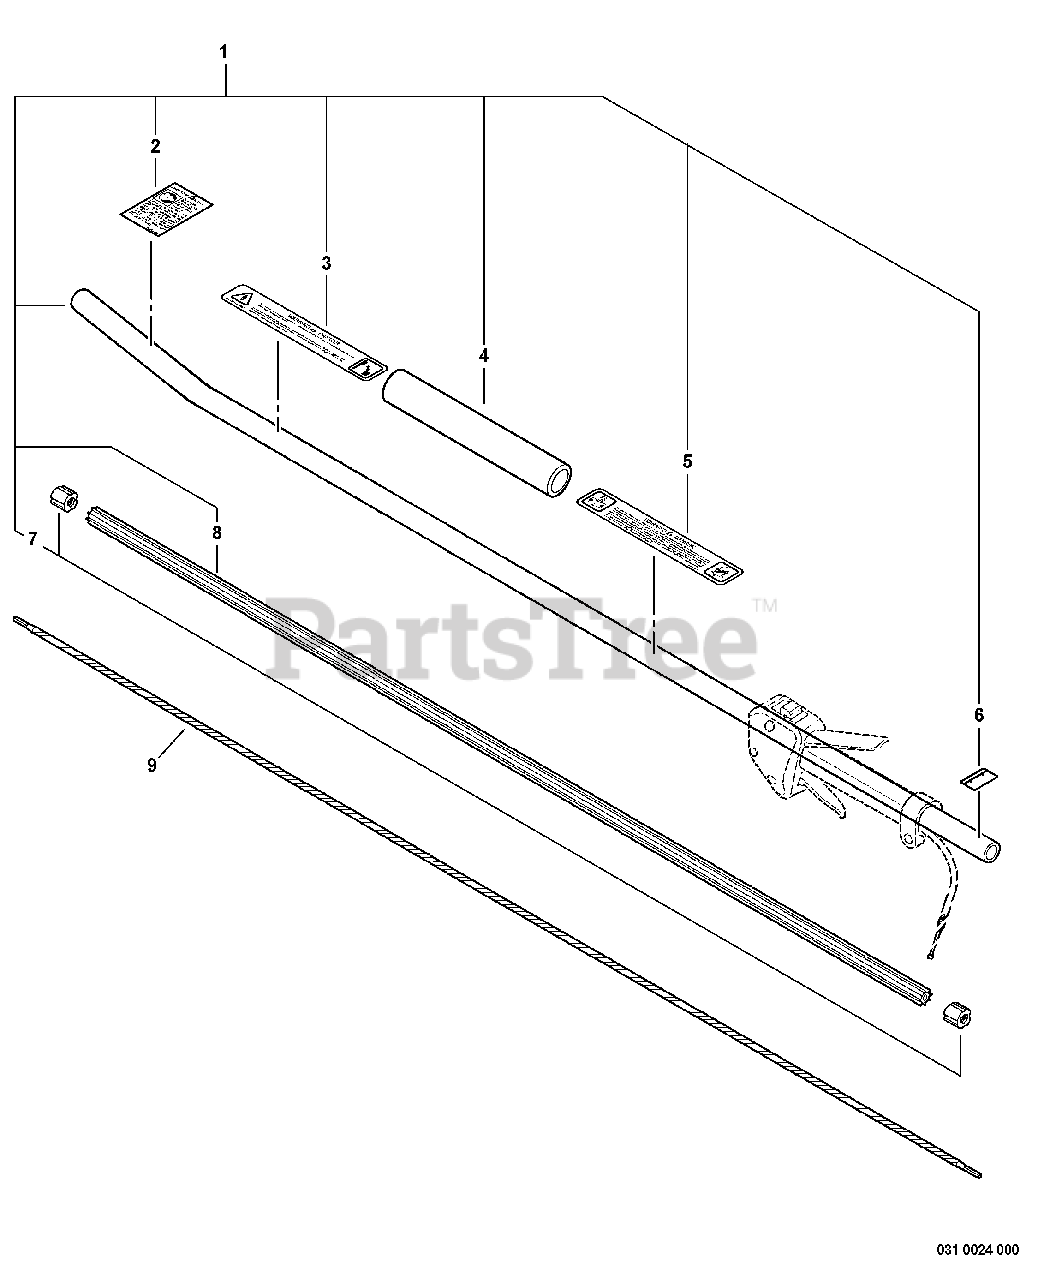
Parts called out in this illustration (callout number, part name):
1	MAIN PIPE ASSY
2	LABEL, CAUTION
3	LABEL - CAUTION
4	GRIP, HANDLE
5	LABEL, CAUTION
6	LABEL - ALIGNMENT
8	LINER - FLEXIBLE
9	DRIVESHAFT - FLEXIBLE
